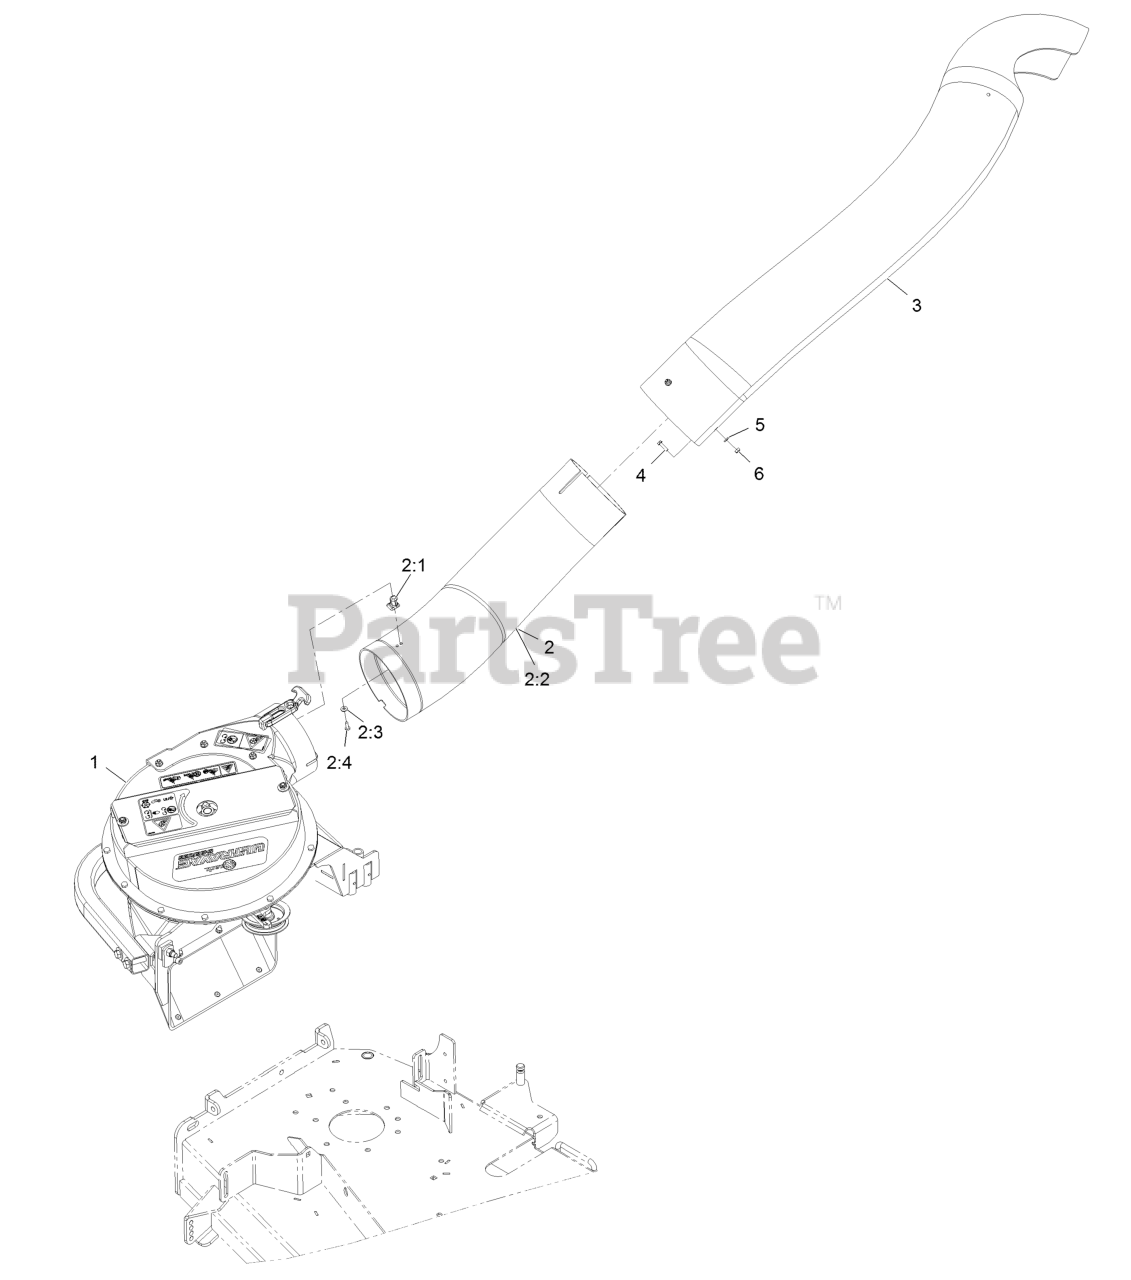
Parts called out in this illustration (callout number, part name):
1	ASM- Blower
2	Lower Tube ASM
2:1	Tube-Lower, Short
2:2	Latch-Keeper
2:3	Screw-PPH #10-24 X 5/8
2:4	Washer-#10 Std
3	Tube-Upper
4	Screw-HWH #10-24 X 3/4
5	Washer-#10 Std
6	Nut-Nyloc #10-24
